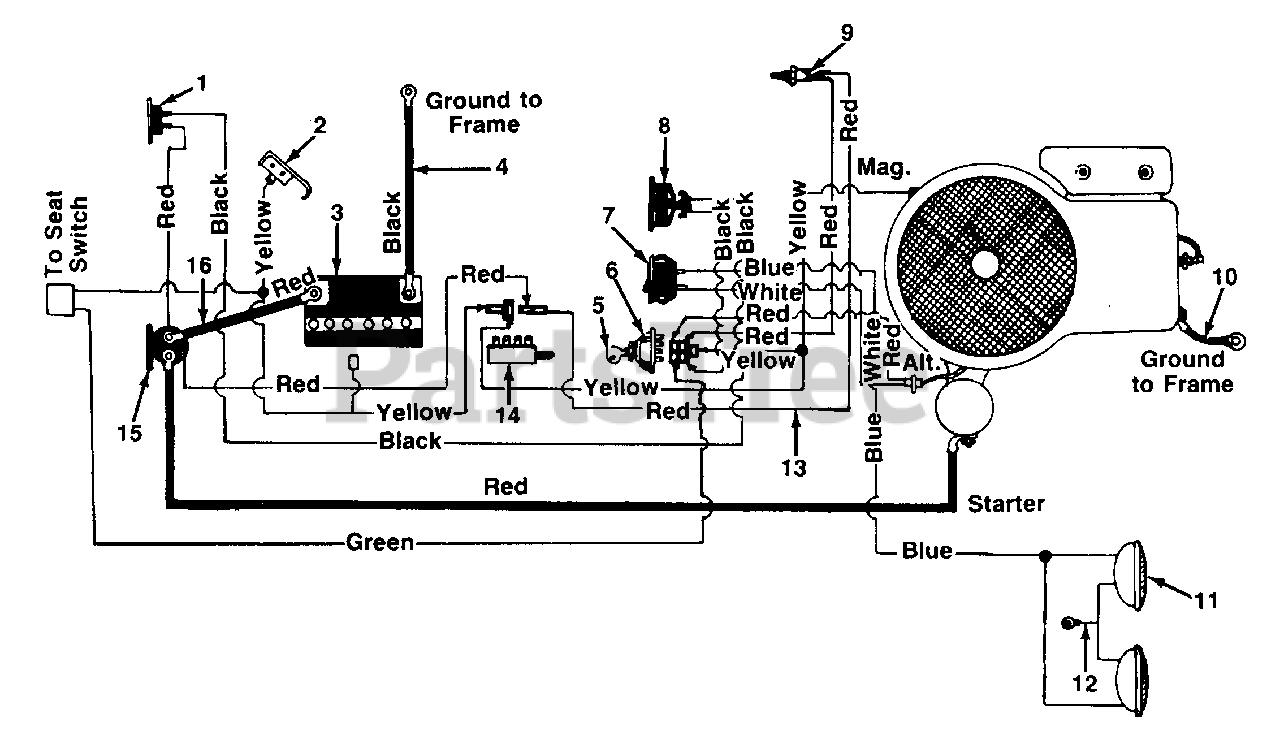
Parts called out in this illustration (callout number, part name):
1	Circuit Breaker
2	Spring Switch
3	2V-Battery
4	Grounding Wire 9.0" Lg.
5	Ignition Key
6	Ignition Switch
7	Headlight Switch
8	Ammeter
9	Safety Switch
10	Ground Wire 7.25" Lg.
11	Headlight
12	Ground Wire
13	Wire Harness
14	Safety Switch
15	Solenoid
16	Electric Wire w/ Boot
